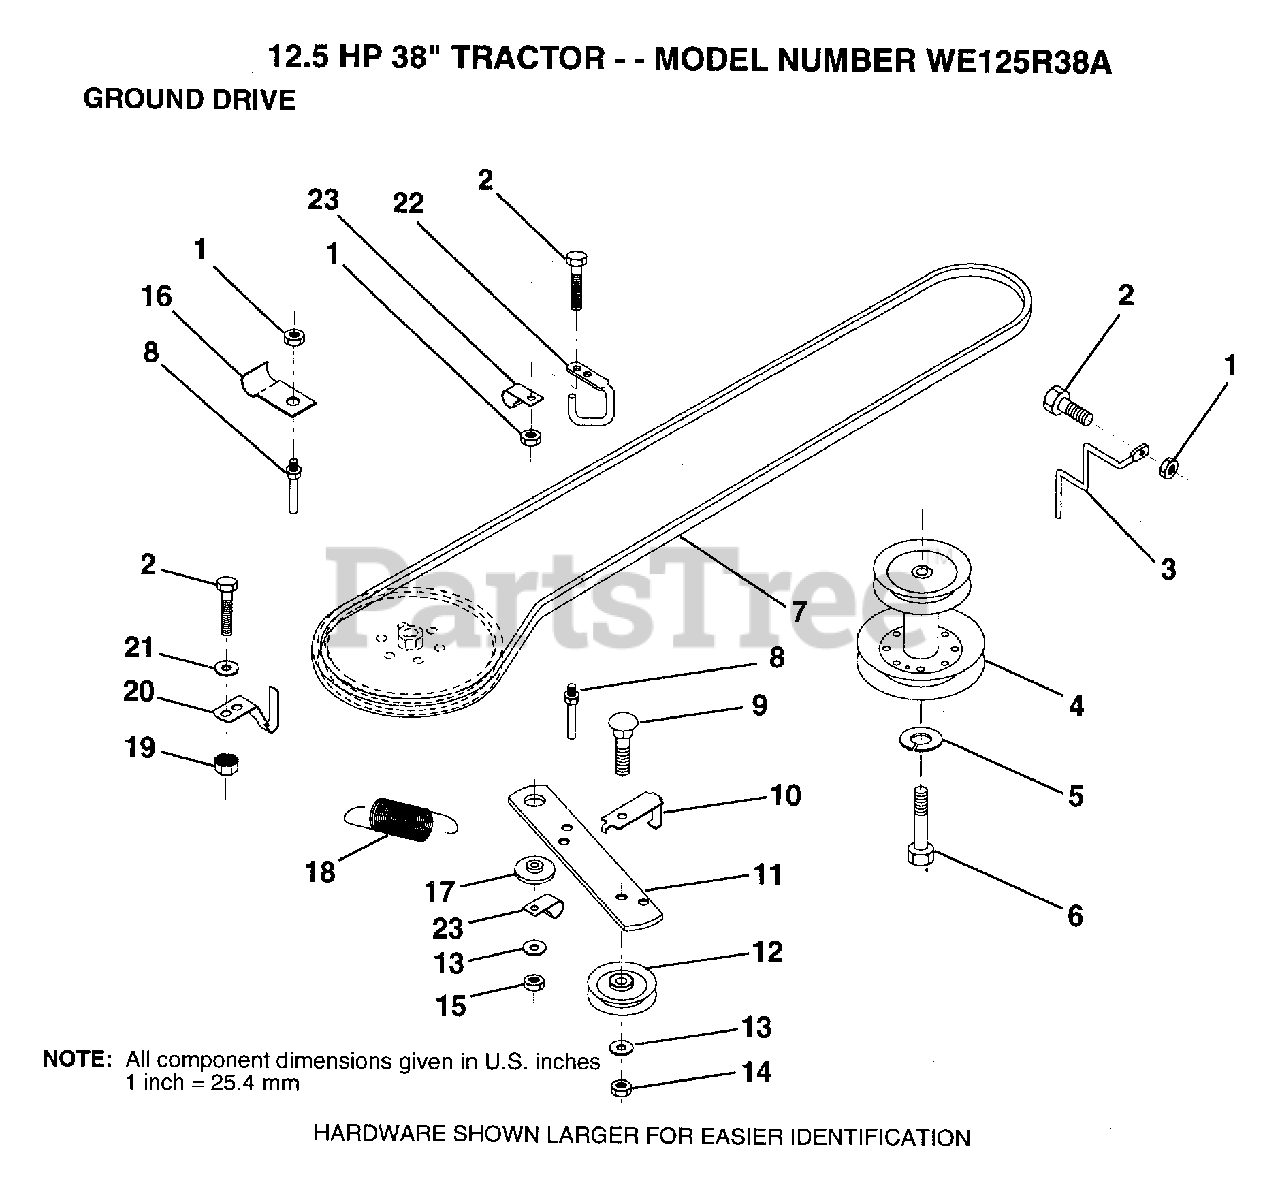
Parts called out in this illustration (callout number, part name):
2	BOLT
3	KEEPER MWR DR BLT
4	PULLEY.ENGINE.LR
5	LOCKWASHER
6	HEX BOLT
7	BELT
8	"KEEPER,DRIVE BELT"
9	BOLT
10	"KEEP,IDLER DR BEL"
12	PULLEY IDLER
13	WASHER
14	LOCKNUT
16	"CLIP,INSULATOR"
17	SPACER RETAINER
20	"KEEPER,DR BELT "
21	WASHER
22	"KEEPER,FRA DR BEL"
23	CLIP INSULATOR
